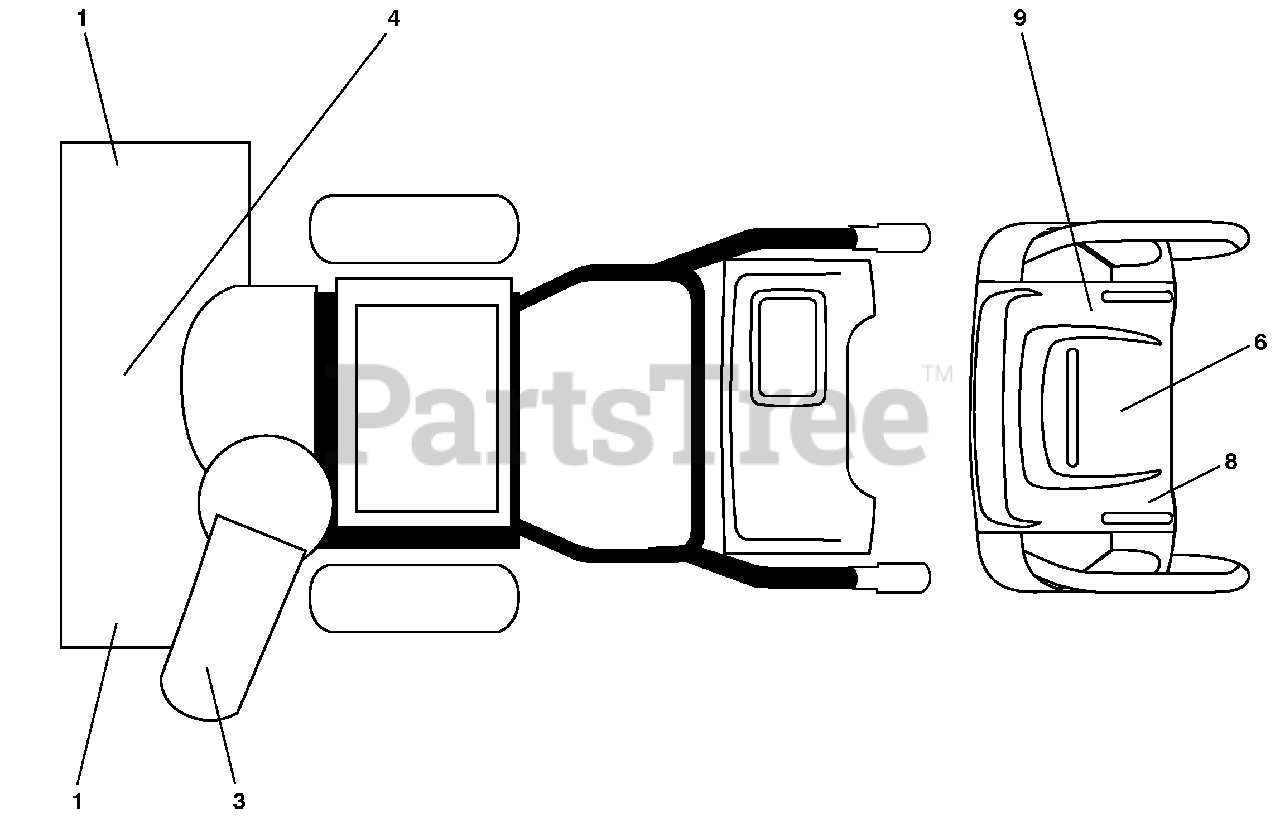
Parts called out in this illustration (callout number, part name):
1	DECAL, DANGER
3	DECAL, DANGER, DEFLECTOR
4	DECAL, DANGER
6	DECAL, INSTRUCTION
8	DECAL, CONS, LT SPD/LEV/PWRST
9	DECAL, CONS, RT SPD/LEV/PWRST
9	DECAL, WARNING SPARK
9	OWNER'S MANUAL, ENGLISH
9	OWNER'S MANUAL, FRENCH
